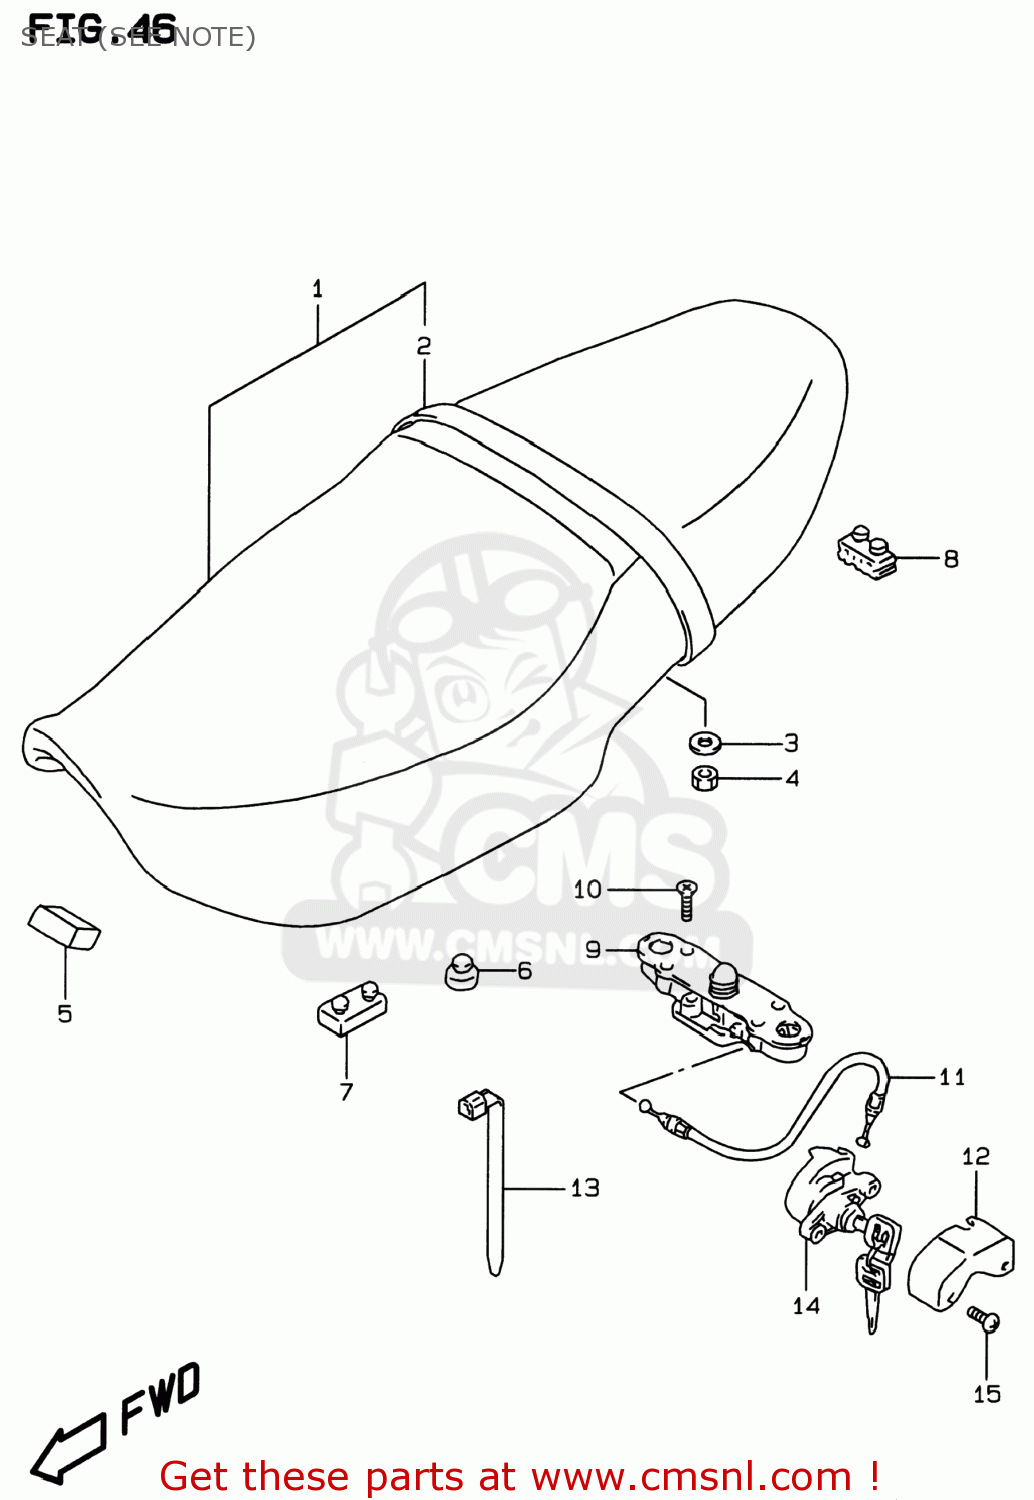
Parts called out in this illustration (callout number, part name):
1	SEAT ASSEMBLY
2	BAND ASSY,SEAT(BLACK)
3	CUSHION
4	CUSHION
5	NUT
6	CUSHION
7	CUSHION
8	CUSHION,SEAT(40X20X15)
9	LOCK ASSY,SEAT STRIKER
10	SCREW 6X30
11	CABLE,SEAT LOCK
12	GUARD,SEAT LOCK
13	LOCK SET,SEAT
14	SCREW(6X14)
